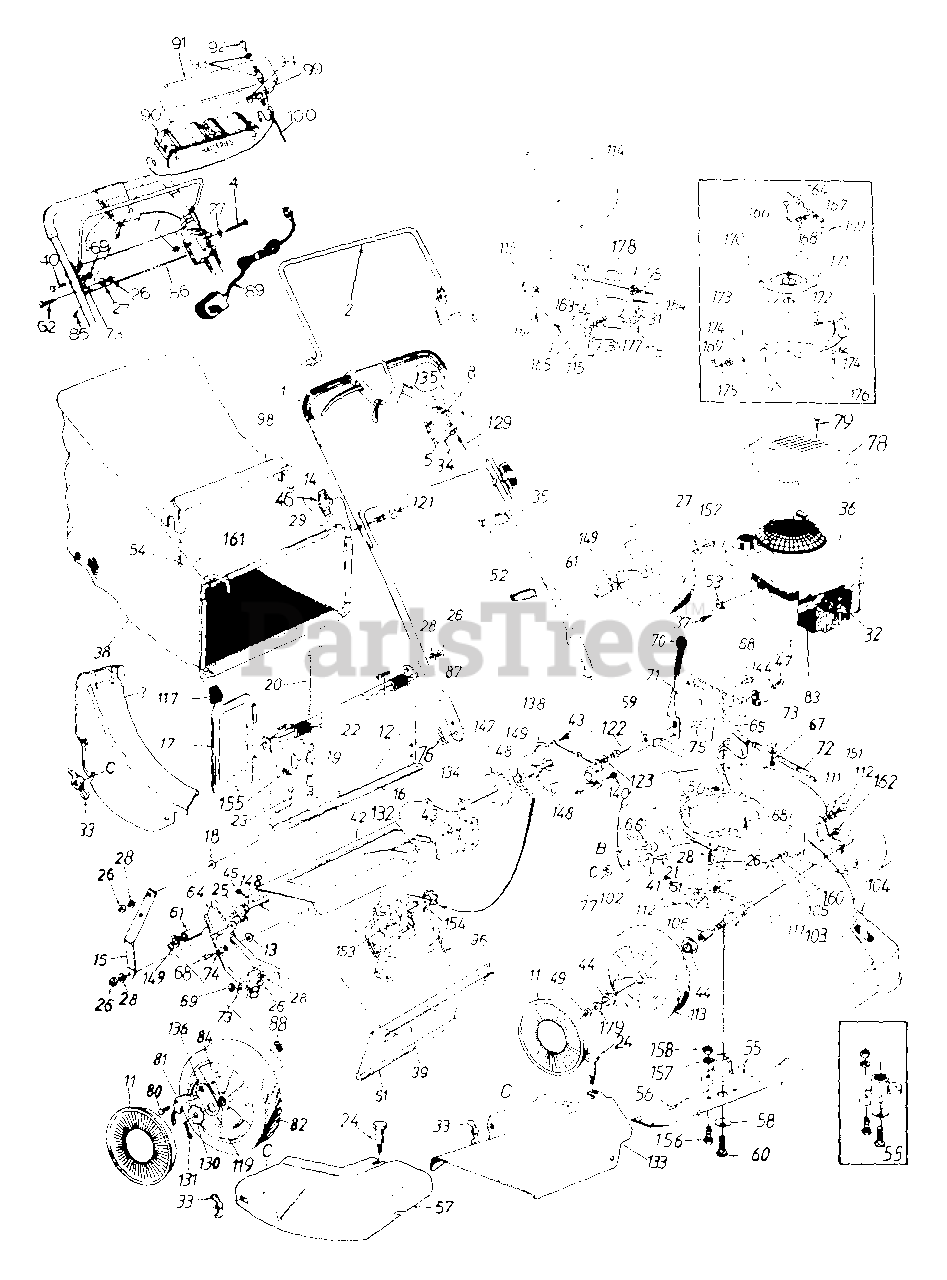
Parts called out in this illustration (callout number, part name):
1	Foam Grip
3	Rear Discharge Chute Ass'y.
4	Hex Bolt 1/4-20 x 2" Lg.
5	Throttle Body
7	Hex L-Nut 1/4-20 Thd.
8	Throttle Lever
11	Hub Cap
12	Truss Mach. Scr. 1/4-20 x .62" Lg.
13	Fl-Wash..383" I.D. x 1" O.D.
19	Torsion Spring
20	Pivot Pin
21	Carriage Bolt 1/4-20 x .62"
22	Truss Mach. Scr. 1/4-20 x 3/4" Lg.
23	Hex Bolt 1/4-20 x .50" Lg.
24	Shoulder Bolt .312 Dia. x .18 Lg.
25	Hex Bolt 1/4-20 x .62" Lg.
26	Hex Nut 1/4-20 Thd.
27	Bell-Wash. 1/4" I.D.
28	L-Wash. 1/4" I.D.
31	S.P. Control Cover
32	Spark Plug Insulator
33	Wing Nut w/Washer
34	Throttle Control Wire 61"
36	Engine
37	Hex Self-Tap Scr. #10-32 x .62" Lg.
38	Grass Bag
39	Retaining Strip
40	Curved Carr. Bolt 5/16-18 x 1.38" Lg.
41	Fl-Wash..344" I.D. x .62"
44	Ball Bearing 1/2" I.D.
45	Hex AB-Tap Scr. 1/4 x .62"
46	Hand Knob
47	Hex Patch L-Nut 3/8-24 Thd.
48	#48 Chain .500" Pitch x 30 Links
49	Hex L-Nut 1/2-20 Thd.
51	Rear Flap 3.75" x 17.30" Lg.
52	Cable Tie
53	Cable Clamp
54	Hex AB Scr. #12 x 1.25" Lg.
55	Blade Adapter Kit
56	21" Mulching Blade
57	Mulching Plug
58	Bell-Wash..46" I.D.
59	Height Adj. Connecting Arm
60	Hex Bolt 7/16-20 x 1.5" Lg. (Grade 5)
61	Spacer .513" I.D. x .703" O.D. x .69" Lg.
62	Carr. Bolt 1/4-20 x 1.25" Lg.
64	R.H. Handle Wheel Brkt. Ass'y.
65	L.H. Handle Wheel Brkt. Ass'y.
66	Carriage Bolt 5/16-18 x .62"
67	Hex Wash. Hd. B-Tap Scr. 5/16-18
68	Hex Wash. Hd. TT-Tap Scr. 3/8-16
69	Hex Nut 5/16-18 Thd.
71	Height Adj. Lever
72	Extension Spring .75" O.D. x 8" Lg.
73	Bell-Wash. 5/16" I.D.
74	Spacer
75	Shld. Spacer .500" Dia.
76	Hairpin Clip
77	Bolt Retainer 1/4 x .50" O.D.
78	Engine Shroud
79	Screw #10 x 1.25" Lg.
80	Shld. Scr..342" Dia. x .268
81	Pawl
82	Rear Wheel Ass'y. Comp.
83	Clamp
84	Bearing 1/2" I.D.
85	Truss Mach. Tap Scr. 1" Lg.
88	Weld L-Nut 1/4-20 Thd.
89	Battery Charger
90	Battery Pack - 12 Volt
91	Battery Tray
92	Ignition Key
93	Ignition Switch
94	Fuse Holder
95	S.P. Cable
96	"V"-Belt
98	Bag Handle
99	Plug
100	Wire Harness
102	21" Deck Ass'y.
103	Shld. Bolt .5" Dia. x .295
104	Bell-Wash..515" I.D. x 1.0" O.D.
105	Front Axle Ass'y.
106	Sleeve.526" I.D. x.690" O.D. x .880" Lg.
111	Intern. L-Wash. 3/8 I.D.
112	Shld. Bolt .575" Dia. x .42
113	Front Wheel Ass'y. Comp.
114	Self-Propelled Control Cover
115	Self-Propelled Control Cover
116	Control Lever
117	Door Grip
118	Fl-"C"-Sunk Hd. Tap Scr.
119	Pawl Plate
121	Curved Hd. Bolt 5/16-18 x 2" Lg.
122	Shld. Pin 3/8-24 x 1.43" Lg.
123	L-Wash. 3/8" I.D.
129	Control Cable 43" Lg.
130	Ratchet Wheel 1.62" O.D.
131	Cotter Pin 1/8" Dia. x 1.00" Lg.
132	Hex Jam Nut 3/8-24 Thd.
133	Side Chute Deflector Ass'y.
134	Hex Flange Bearing
135	Throttle Box Comp.
136	Spring - Nylon
144	Fl-Wash..385" I.D. x .87"
147	Rear Shaft Ass'y. 21.94" Lg.
148	Hex Flange Bearing .506" I.D. Plastic
149	Fl-Wash..531" I.D. x .930"
151	Flanged Nyliner Brg.
152	Hex Bolt 1 4-20 x .62" Lg. (Grade 5)
153	Transmission Comp. (See Breakdown)
154	Hex Bearing Cup
155	Hex B-Tap Scr. #10 x .38
156	Hex Scr. 3/8-24 x 1.0" Lg.
157	L-Wash. 3/8" I.D.
158	Hex Nut 3/8-24 Thd.
160	Fl-Wash..51" I.D. x .75" O.D.
162	Hex Jam Nut 3/8-16 Thd.
163	3 Tooth Rack Gear Insert
164	Spd. Control Cable - 50" Lg.
165	6-Spd. Shift Lever
168	Hex Cent. L-Nut 1/4-20 Thd.
169	Cot-Pin 3/32" Dia. x .75" Lg.
170	Shift Rod
171	Movable Pulley Half Ass'y.
172	Carr. Bolt 1/4-20 x .50" Lg.
173	Spined Pulley Half
174	Flanged Bushing
175	Fl-Wash..328" I.D. x .68" O.D.
178	6-Speed Rack Cable Brkt.
17055B-0637	AXLE ASSY-CHAIN - POWDER BLACK (0637)
17055B-0638	AXLE ASSY-CHAIN - MTD/TROY-BILT RED (0638)
17055B-0665	AXLE ASSY-CHAIN - YARDMAN GREEN (0665)
